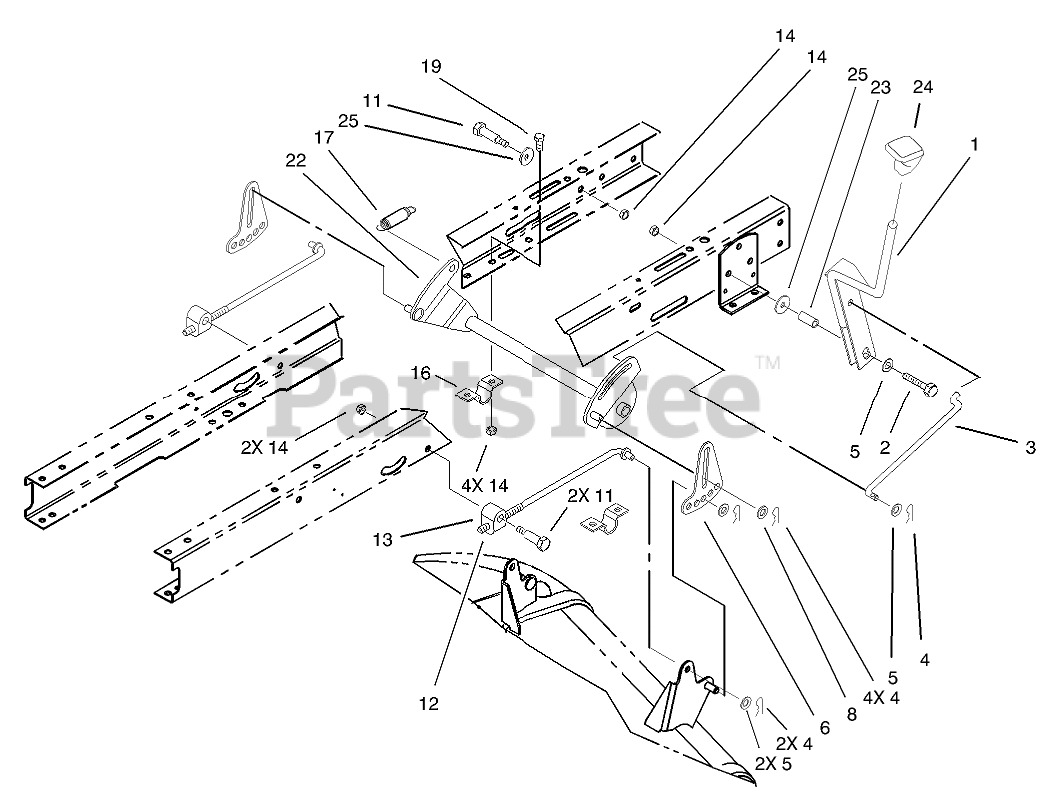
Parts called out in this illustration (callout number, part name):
1	HOC LEVER ASM
2	SCREW-HH
3	LINK-HOC
4	PIN-COTTER
5	WASHER-FLAT
6	LINK-ADJUSTING, HOC
8	WASHER-HARDENED
11	SCREW-SHOULDER, HH
12	ROD-HANGER, REAR
13	TRUNNION-HOC
14	NUT-LOCK, NI
16	CLAMP-PIVOT, HOC
17	SPRING-EXTENSION
19	SCREW-HH
22	PIVOT ASM
23	SPACER
24	KNOB-SHIFT
25	WASHER-PIVOT
